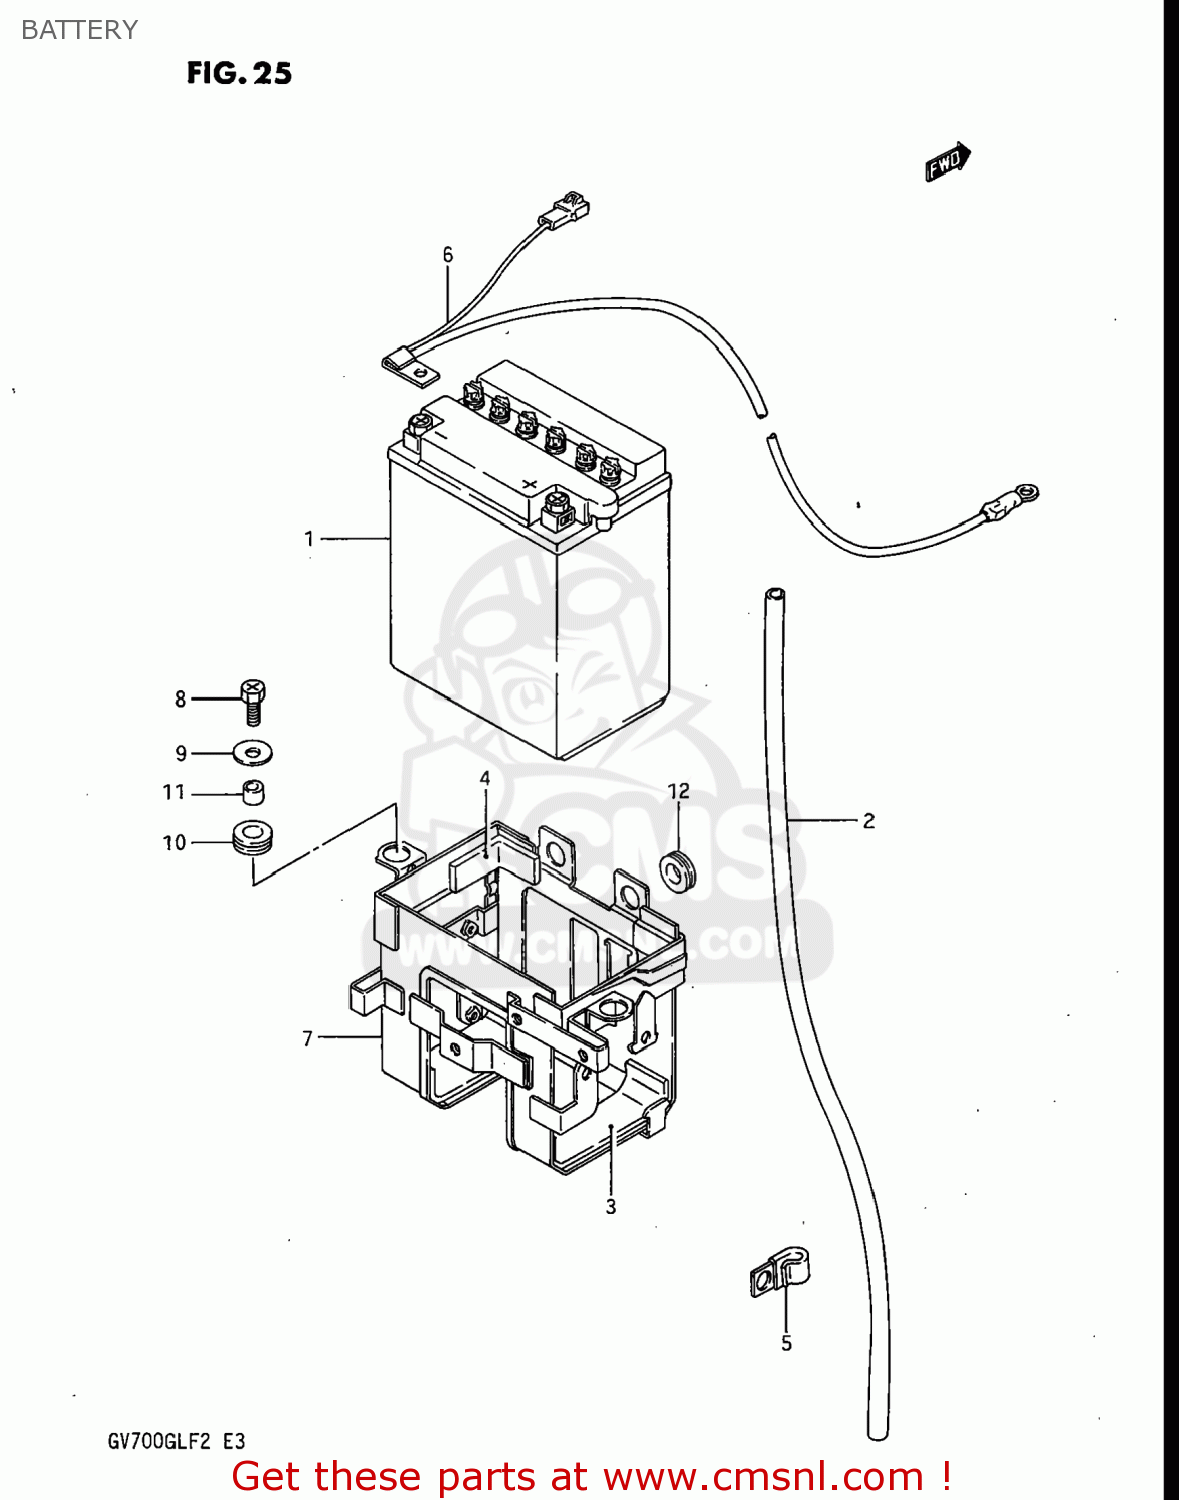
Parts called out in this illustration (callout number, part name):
1	BATTERY ASSEMBLY (12V)
2	HOSE,BATTERY EXHAUST
3	PROTECTOR(170X95X3.0)
4	PROTECTOR,20X9
5	CLAMP
6	WIRE,BATTERY MINUS LEAD
7	HOLDER,BATTERY
8	SCREW
9	WASHER
10	CUSHION
11	SPACER(6.1X9X7.5)
12	GROMMET
